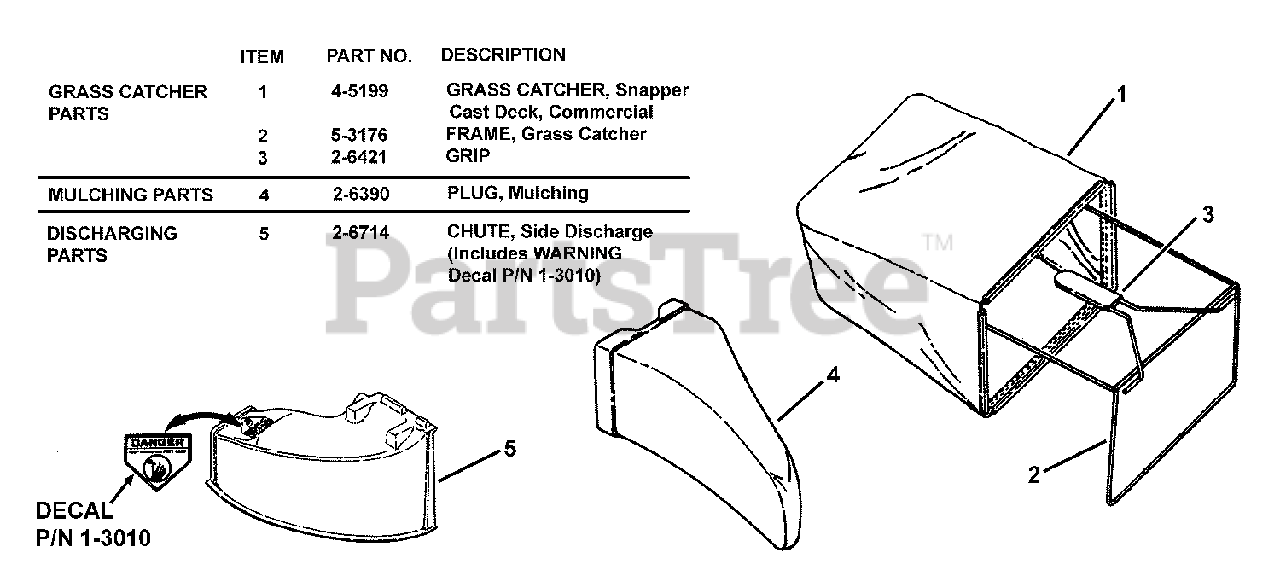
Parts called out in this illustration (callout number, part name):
1	GRASS CATCHER, SNAPPER Cast Deck Commercial
2	ASSEMBLY, Catcher Frame
3	GRIP
4	PLUG, Mulching
5	CHUTE, Side Discharge
